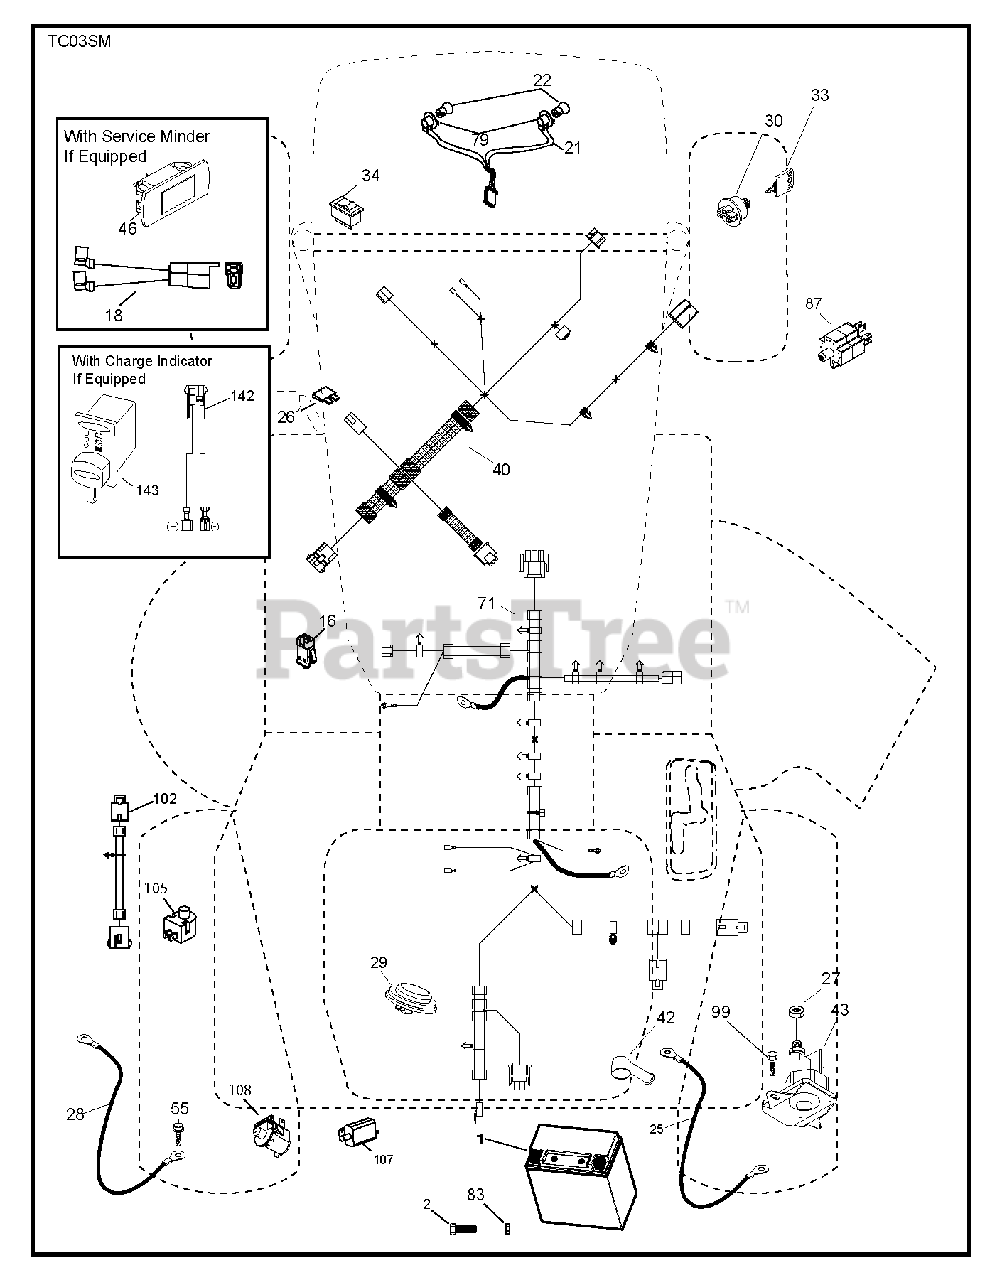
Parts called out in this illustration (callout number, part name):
1	BATTERY BATTERY 14AH 12V LEOC
2	SCREW.HEX.HEAD.CAP.M6 X1.12W
16	SWITCH INTERLOOK PUSH-IN
21	HARNESS.LIGHT W/4152J BULBS
25	CABLE.BATT.8GA.RED9.C
26	FUSE 20AMP
27	NUT
28	CABLE.BATT.BLCK10.SLV
29	SWITCH.SEAT.DELTA.OPC.
30	SWITCH.IGN.DELTA.W.LGH.ROS
33	KEY.CHAIN.BLISTER.PACK.GEN.INT
40	HARN.DASH.CRD.CC.SQ.RDSTRT
42	TERMINAL COVER
43	SOLENOID.STARTER.BRASS.PLUNGER
55	SCREW 5/16"
71	HARNESS.CHASS.CRD.TEX.RDY.STRT
79	BULB HOLDER ASM.
83	NUT NUT SQUARE
87	RP SWITCH.RAILMOUNT.NO-NC-NC
99	SCREW
102	HARNESS ASSY
105	REVERSE SWITCH
107	.WITCH.FULL BAGGER.INDICATOR
108	SWITCH.SNAPMOUNT.NC
142	CHARGE.PORT.PIGTAIL HARNESS
143	CHARGE.PORT
